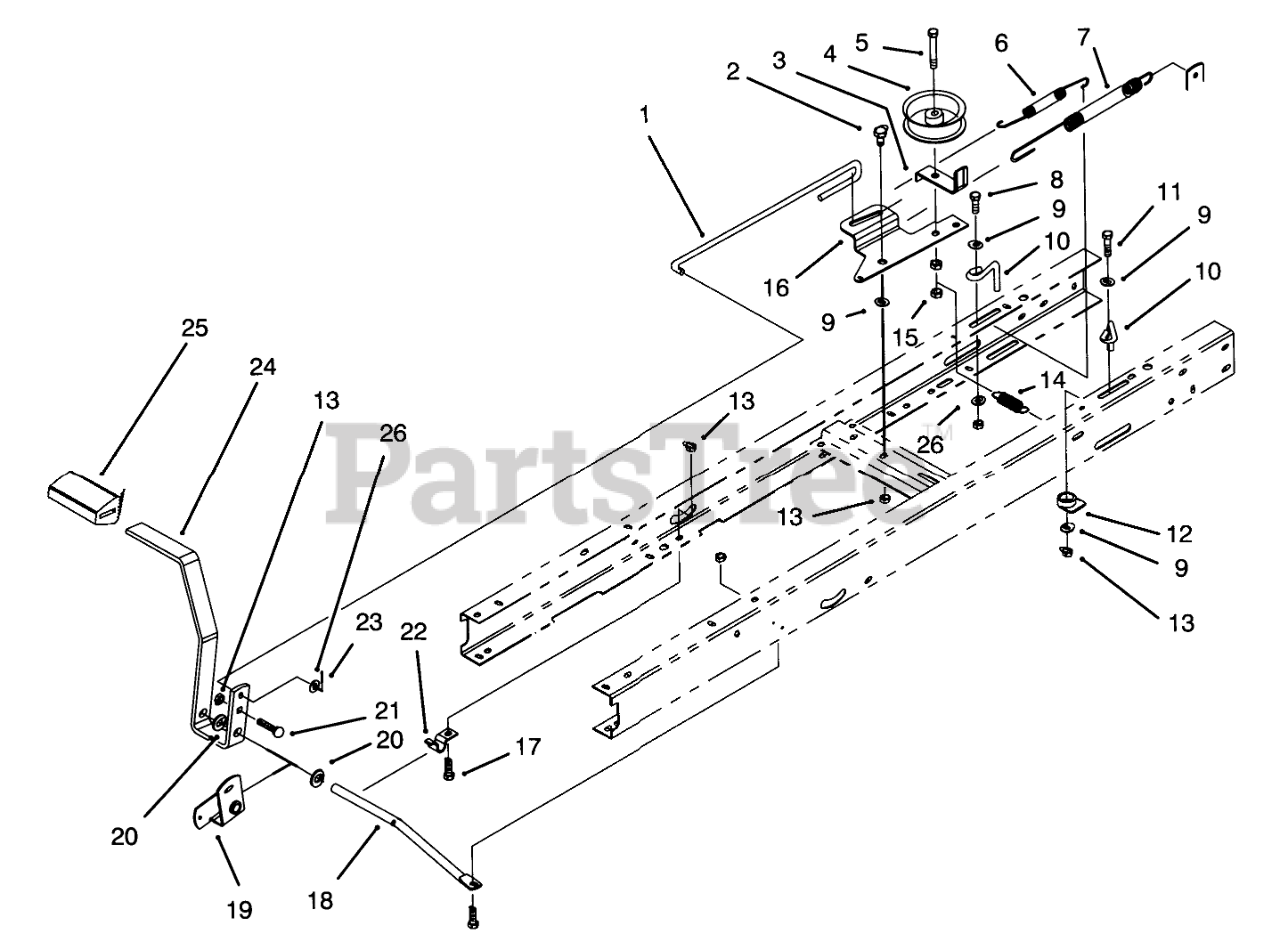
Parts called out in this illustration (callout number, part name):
1	ROD-CLUTCH/BRAKE
2	BOLT-SHOULDER
3	GUIDE-IDLER, BELT
4	Idler Pulley
5	SCREW-HH
6	SPRING-EXTENSION
7	BRAKE SPRING
8	SCREW-HH
9	WASHER-PIVOT
10	TRANS BELT GUIDE
11	SCREW-HH
12	GUIDE-CABLE
13	NUT-LOCK, NI
14	SPRING-EXTENSION
15	NUT-LOCK, NI
16	ARM-IDLER
17	SCREW-HH
18	ROD-PIVOT, PEDAL
19	BelIcrank
20	WASHER-FLAT
21	SCREW-CARR
22	CLAMP-PIVOT, SHIFT
23	PIN-COTTER
24	Pedal-Clutch/Brake
25	PAD-PEDAL
26	WASHER-PLAIN
